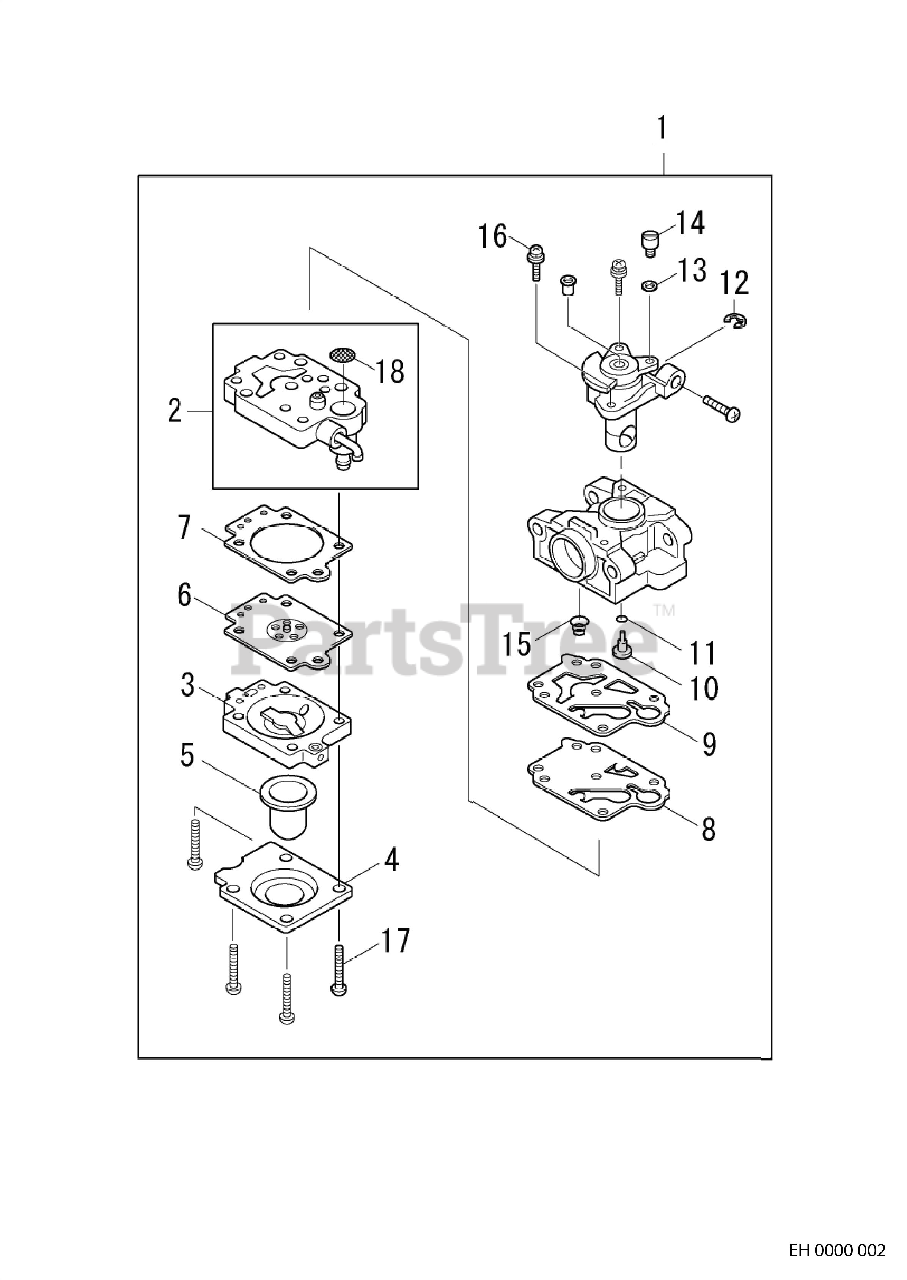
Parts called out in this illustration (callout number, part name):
1	CARBURETOR - WYL174
2	PUMP BODY ASSEMBLY
3	PURGE BODY ASSY
4	COVER,PRIMER PUMP
6	METERING DIAPHRAGM ASSY
7	GASKET, METERING DIAPHRAGM
8	DIAPHRAGM, PUMP
12	RING, SPRING RETAINING
